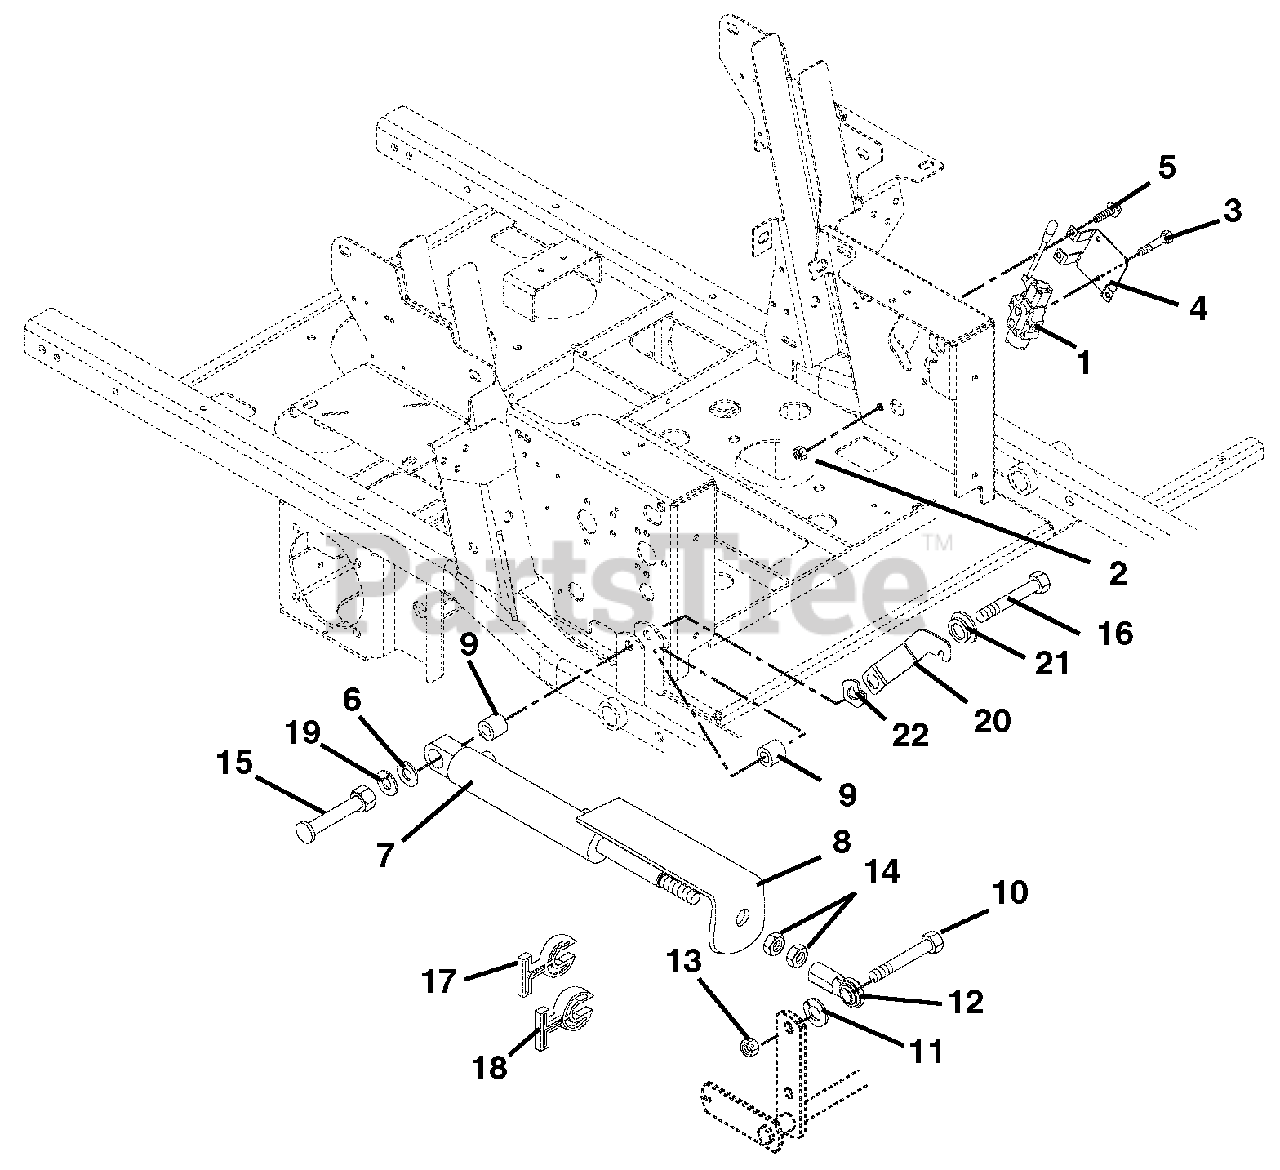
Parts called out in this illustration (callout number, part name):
1	Valve, Hydraulic
2	Nut, Locking Top Flange .31-18
3	Bolt, Hex .31-18 x 2.25 Grade 5
4	Bracket, Valve Mounting
5	Screw, Tapping .38-16 x .50 Hex Washer Head
6	Washer, Flat Steel .515 x 1.625 x .25
7	Cylinder, Hydraulic Lift
8	Strap, Cut Indicator / Guard
9	Bushing .516 x 1.00 x 1.05
10	Bolt, Hex .62-11 x 2.25 Grade 8
11	Washer, Lock .62 x .156
12	Rod End, Right Hand Female .625
13	Nut, Locking Center .62-11
14	Nut, Jam .625-18
15	Post, Cylinder Stop
16	Bolt, Hex .50-13 x 3.75 Grade 5
17	Stop, Cylinder .34 Thick
18	Stop, Cylinder .68 Thick
19	Washer, Locking .50 x .125 Regular
20	Latch, Footboard
21	Bushing, Flange .515 x .75 x .275 x 1.12
22	Washer, Wave .076 x 1.12 x .08
